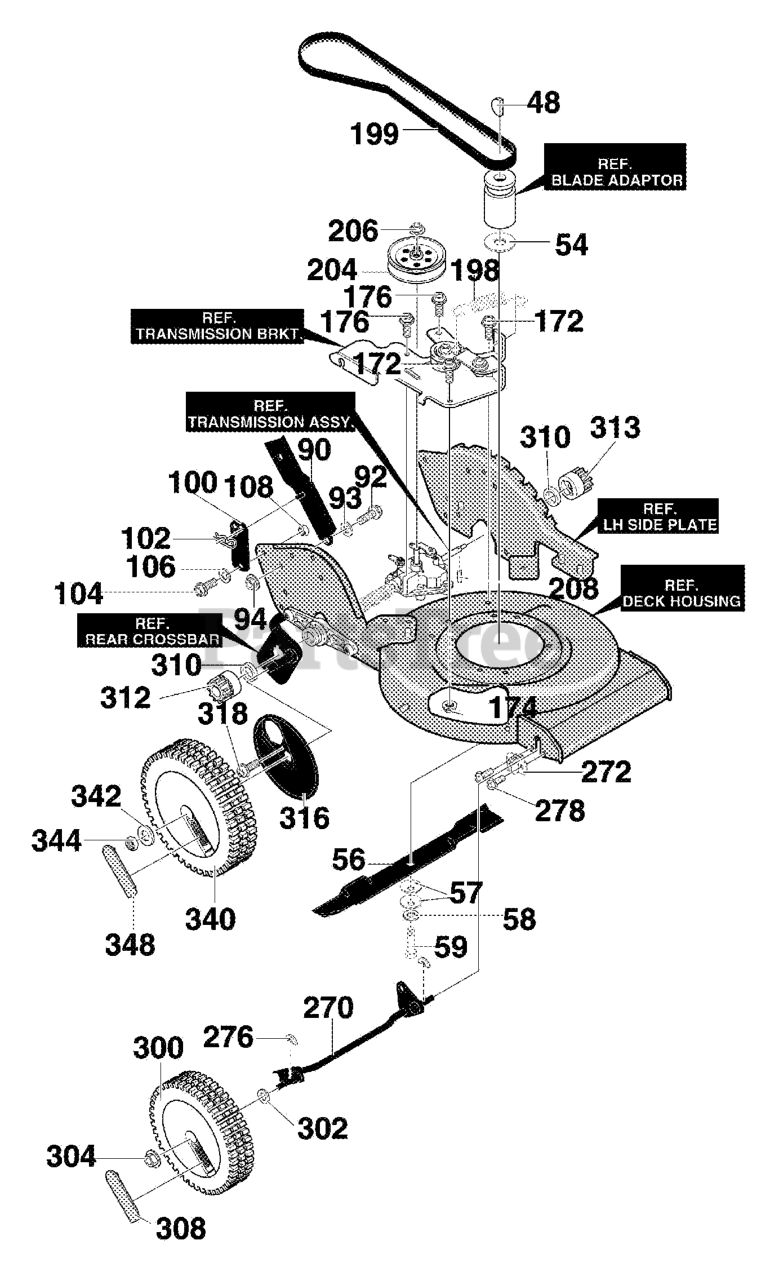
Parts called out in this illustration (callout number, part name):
48	Woodruff Key
54	SPACER, Blade Adapter
56	Blade, 22" Mulch 3N1
57	WASHER, Bellville
58	FLATWASHER
59	SCREW, 3/8-24 x 2.00
90	BRACKET, Assy. Handle
92	BOLT, HHSH 3/8-16
93	WASHER, Spring
94	NUT, 3/8-16
100	Strap, Handle Adjuster
102	HAIR PIN
104	BOLT, HHSH 3/8-16
106	WASHER, Spring
108	NUT, 3/8-16
172	BOLT, HHSH 3/8-16
174	NUT, 3/8-16
176	SCREW, 5/16-18 x 0.75
198	SPRING, Tension
199	BELT, V3L 35.73LH
204	PULLEY, Engine
208	Drive Pin
270	Crossbar, Assy. Front
272	Bushing
276	Clip, Front Axle
278	SCREW, 1/4-20x.63
300	Tire & Rim
302	WASHER Spring
304	NUT, 3/8-16
308	Hubcap, 8"
310	FLATWASHER
312	Gear Pinion, RH
313	Gear Pinion, LH
316	Dustcover, 8" wheel
318	SCREW, 1/4-20x.50
340	WHEEL, Drive
342	FLATWASHER
344	NUT, 3/8-16
348	Hubcap, 8" Wheel
